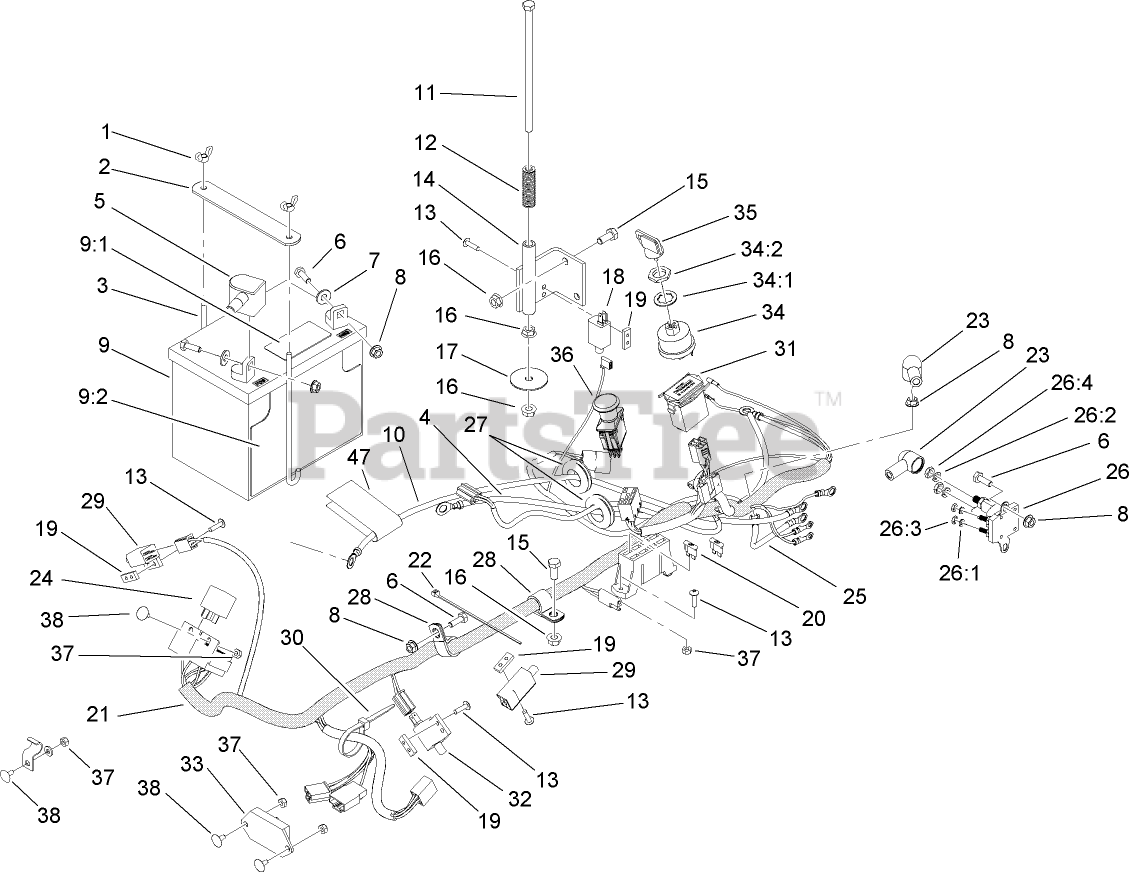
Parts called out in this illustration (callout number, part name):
1	WINGNUT
2	STRAP-HOLDDOWN, BATTERY
3	BOLT-HOLDDOWN
4	CABLE-GROUND, NEGATIVE
5	INSULATOR-BATTERY
6	SCREW-HH
7	WASHER-FLAT
8	NUT-HF
9	BATTERY
9:1	Decal-Battery
9:2	Decal-Battery
10	CABLE-BATTERY, POSITIVE
11	SCREW-HH
12	SPRING-SWITCH, SEAT
13	SCREW-HEAD, TRUSS
14	BRACKET-SWITCH, SEAT
15	SCREW-HH
16	NUT-HF
17	WASHER
18	SWITCH-CLOSED, NORMALLY
19	PLATE-TAPPED
20	FUSE-BLADE TYPE, 20 AMP
21	HARNESS-ELECTRICAL
22	TIE-CABLE
23	INSULATOR-SOLENOID
25	CABLE-STARTER, POSITIVE
26	SWITCH-SOLENOID
26:1	WASHER-LOCK
26:2	WASHER-LOCK
26:3	NUT-HEX
26:4	NUT-JAM
27	GROMMET
28	CLIP-LOOM
29	SWITCH-OPEN, NORMALLY
30	TIE-PLASTIC
31	METER-HOUR
32	SWITCH
33	MODULE-DELAY, SEAT
34	SWITCH-STARTING, KEY
34:1	WASHER-TOOTH, INTERNAL
34:2	NUT-HH
35	KEY-IGNITION
36	SWITCH-PTO
37	NUT-LOCK, NI
38	BOLT-CARR
47	DECAL-INSTRUCTIONS, CHARGING
